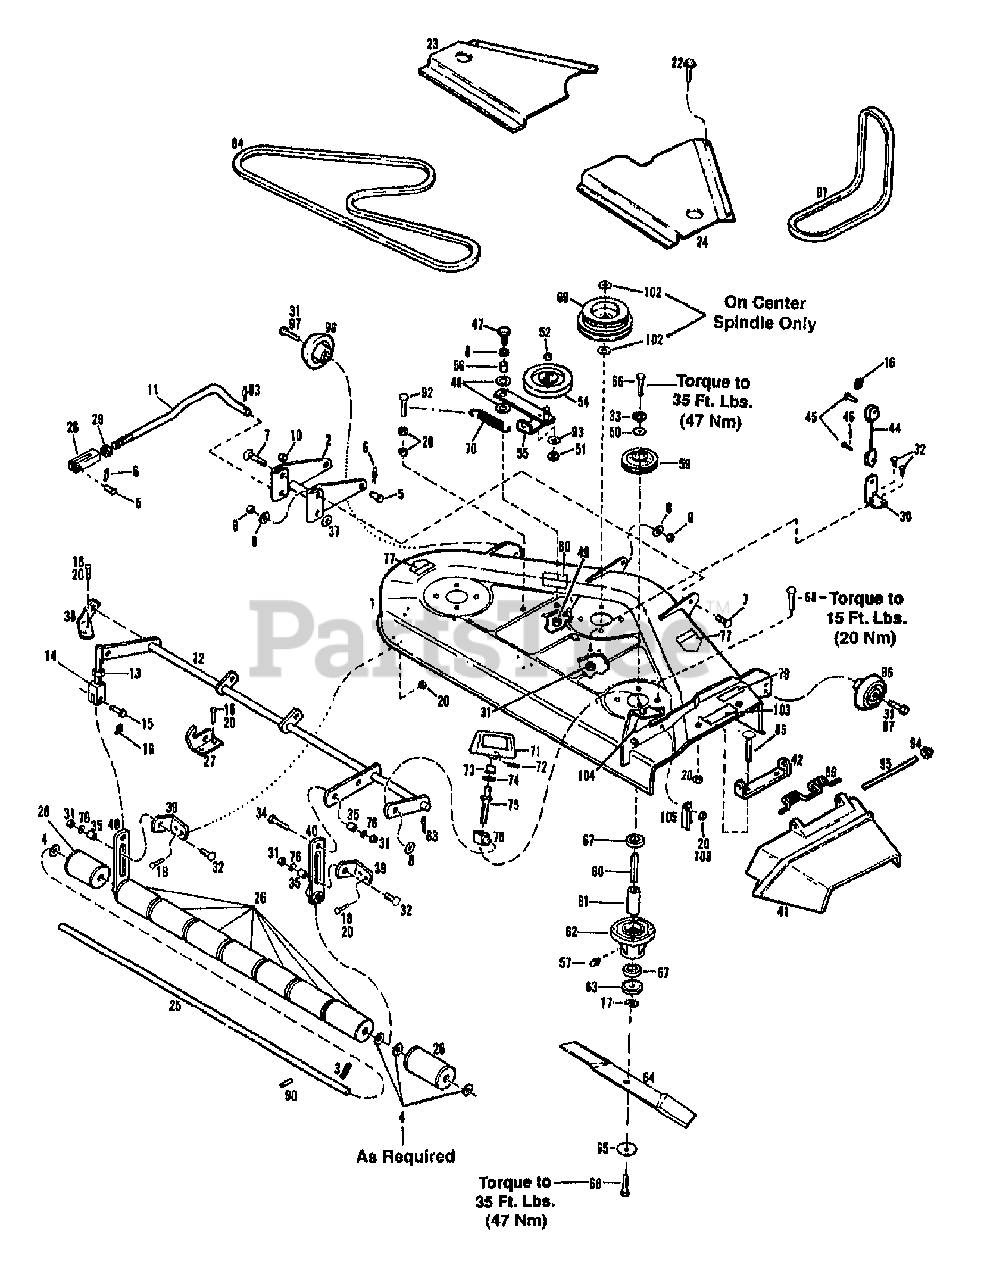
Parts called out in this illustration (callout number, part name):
1	BASE-MOWER W/DECALS
3	PIN-COTTER .125X1.5
4	WASHER-1.38 X.765X .06 ZP
5	PIN-CLEVIS .625X1.44
6	RING-COTTER
7	BOLT-CAR 1/2-13X1-3/4
8	WASHER-1.06X.531X.1 ZP
10	BEARING-SLEEVE
11	ROD-TIE
12	SHAFT-LIFT ADJUST
13	NUT-HEX/JAM 5/8-18 ZP
14	ROD-END
15	PIN-CLEVIS
16	RING-CIRCLE COTTER
17	RING-RETAINING EXT .694 ID
18	SCR-CARR 5/16-18X.75 G2 ZP
20	NUT-TOP/LK 5/16-18 ZP
22	SCR 1/4-20X.5 FL SELF TAP
23	COVER-BELT LH
24	COVER-BELT RH
25	SHAFT-ROLLER
27	ROD-SUPPORT
29	NUT-HEX
30	BRKT-LIFT
31	NUT-LOCK 3/8-16
32	SCR-CARR 3/8-16X1.00
33	WASHER-LK .438 ZP
34	SCR-HH 3/8-16X1.25
35	SPACER-.5X.39X.307
37	WASHER-1.305X.649X.098 ZP
38	BRKT-ROD ADJUST
39	BRKT-ROLLER
40	PLATE-ADJUSTMENT
41	DEFLECTOR-DISCHARGE
44	CABLE-LIFT
45	PIN-CLEVIS .375 X .937 ZP
46	PIN-COTTER .09X.75 ZP
47	SCR-HH 1/2-13X1.5 G5 ZP
48	WASHER
49	NUT-TOP LOCK 1/2-13 ZP
50	WASHER-1.25X.5X.083 ZP
51	BUTTON-WEAR
52	NUT-JAM
54	PULLEY-IDLER
55	ASSM-IDLER ARM
56	SLEEVE-BEARING
57	FITTING-GREASE 1/4-28X2.00
59	ASSM-SHEAVE DRIVE
60	SHAFT-SPINDLE
62	HOUSING-SPINDLE
63	SPACER-BLADE
64	BLADE-CUTTER
65	WASHER-BELLEVILLE
66	SCR-HH 1/2-14X1.00
67	BEARING-BALL
68	SCR-HFLK 5/16-18X.75
69	SHEAVE-DRIVE
70	SPRING
71	HANDLE-HEIGHT ADJ
72	PIN-ROLL .188X1.0
73	SPACER-HANDLE
74	WASHER-FLAT .88X.5X.06 ZP
75	ROD-ADJUSTING
76	WASHER-FLAT 5/16 SAE
77	DECAL-OPEI CAUTION
78	BLOCK-PIVOT
79	DECAL-CUTTING LINE
80	DECAL-BELT DRIVE
83	PIN-COTTER .120X1.00 ZP
85	BOLT-CARR 5/16-18X.63 ZP
89	SPRING-TORSION
90	PIN-DRIVE
92	SCR-HH 5/16-18X1.25 G5ZP
93	WASHER-.505X.22X.05
94	NUT-PUSH 3/8 ZP
96	WHEEL-GAGE
97	SCR-SHLDR 3/8-16
102	WASHER-KEYED SPECIAL
103	DECAL-DANGER
104	DECAL-HEIGHT ADJUST
105	RETAINER-SHAFT
106	SCR-HH 5/16-18X.63 G5
